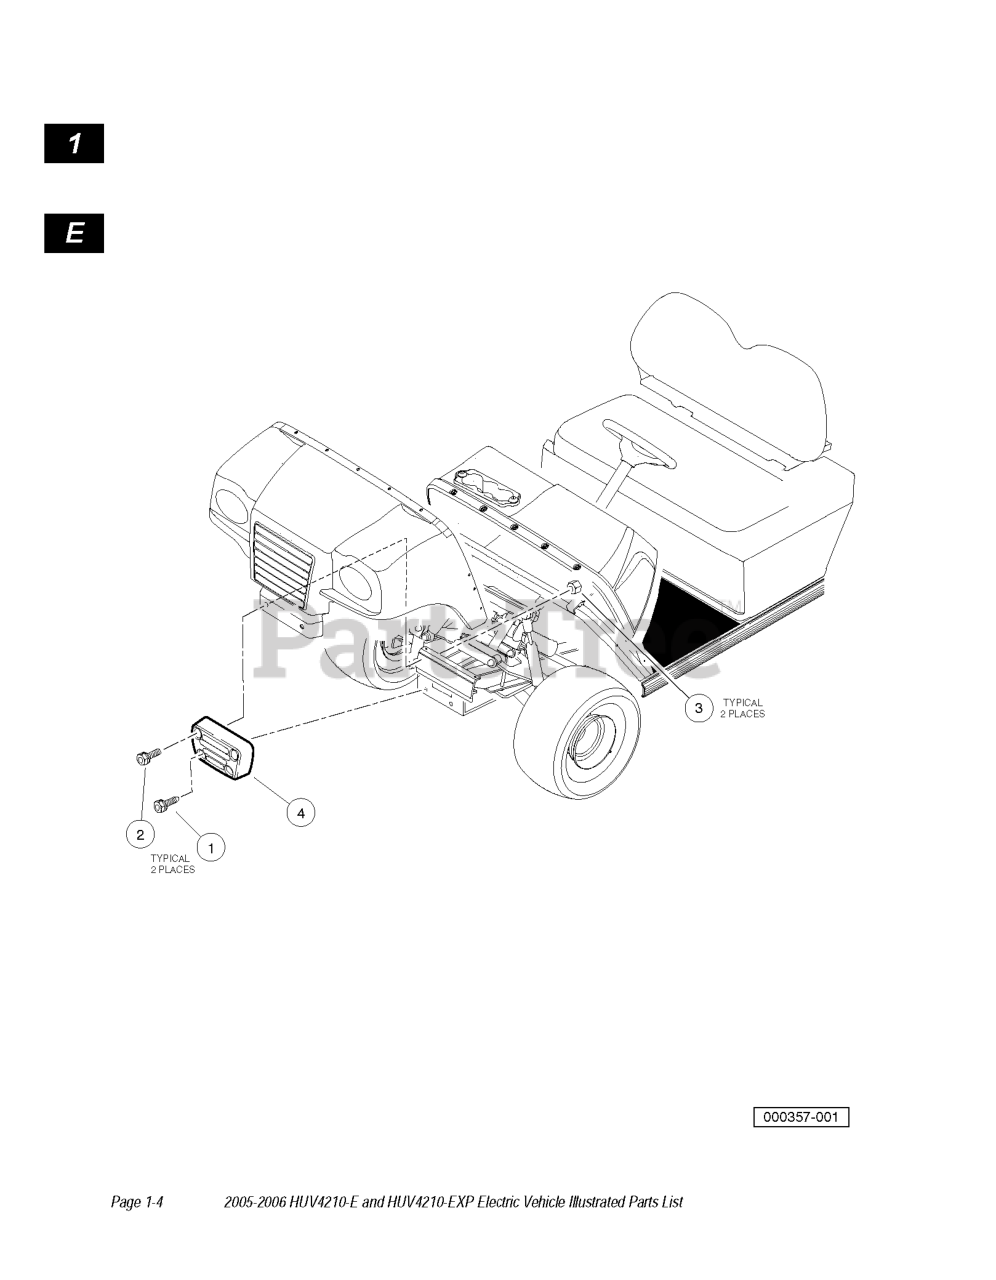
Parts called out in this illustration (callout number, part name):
1	SCREW, M8 X 1.25 X 30 TRI, BLK
2	BOLT, FLANGE HD, M8 X 40.0
3	LOCK NUT, FLG M8 X 1.25 NYLON
4	BUMPER CAST
